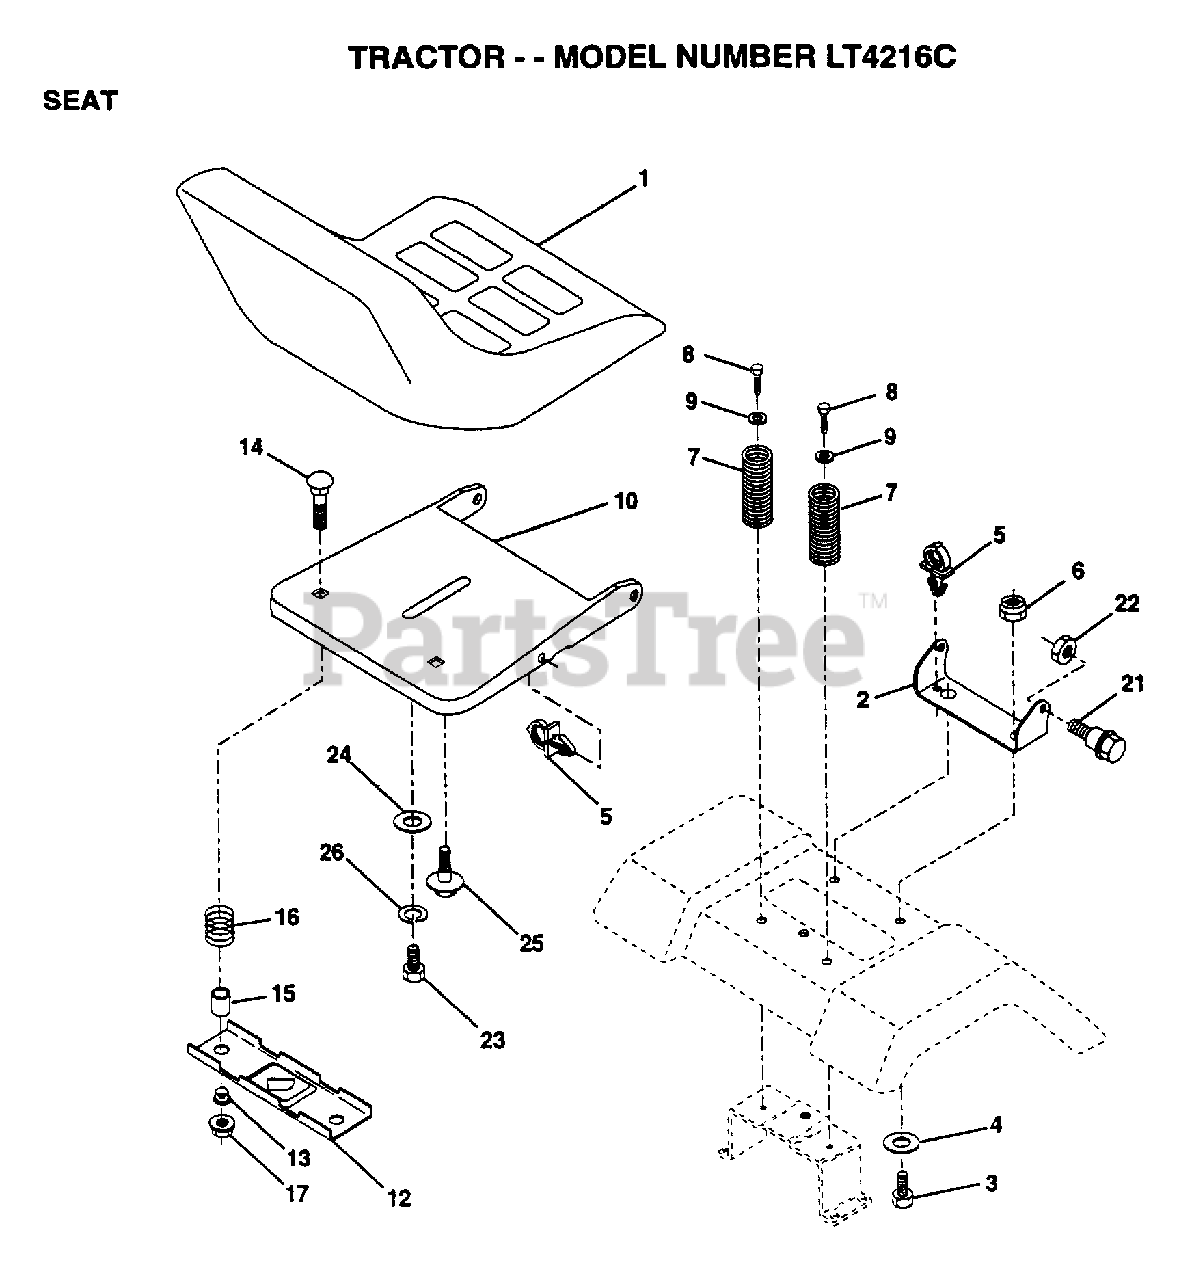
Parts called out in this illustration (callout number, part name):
2	BRACKET PVT SEAT
3	BOLT
4	WASHER PM
5	CLIP.PUSH-IN.HING
6	NUT
7	SPRING COMPRESSIO
8	SCREW GTV
9	WASHER
12	BRKT SWITCH
13	BUSHING
15	SPLIT SPACER
16	SPRING
21	BOLT.SHLD.5/16-18
22	NUT
23	BOLT
24	WASHER
25	"BOLT,SHOULDER"
26	LOCKWASHER
